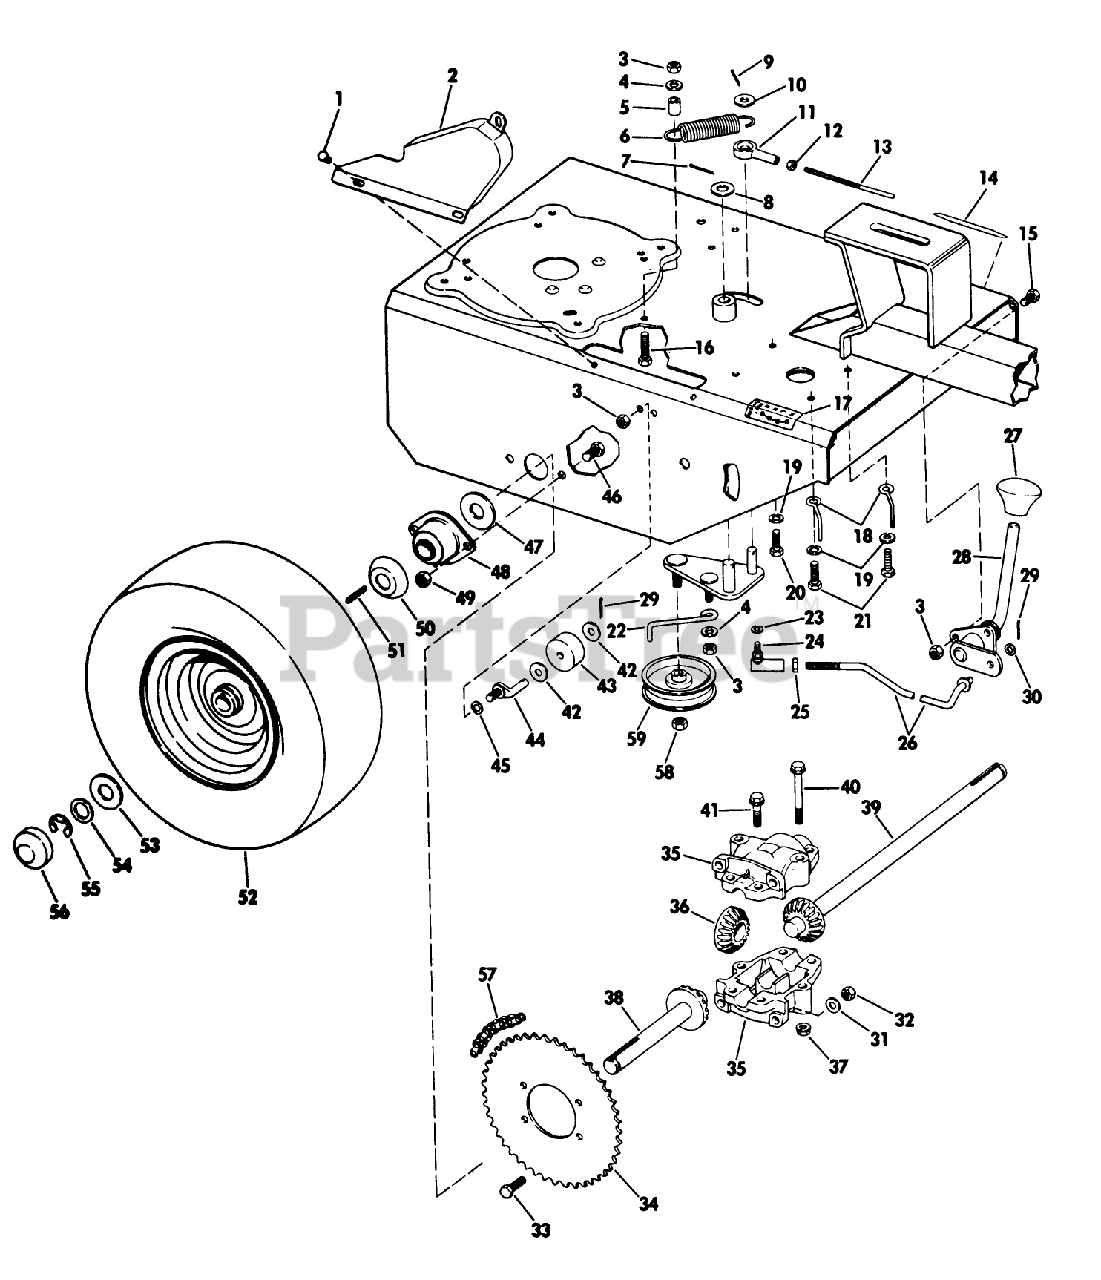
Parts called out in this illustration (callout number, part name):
7	Cotter Pin
9	Cotter Pin
25	Jam Nut
45	Lockwasher
49	LOCKNUT
